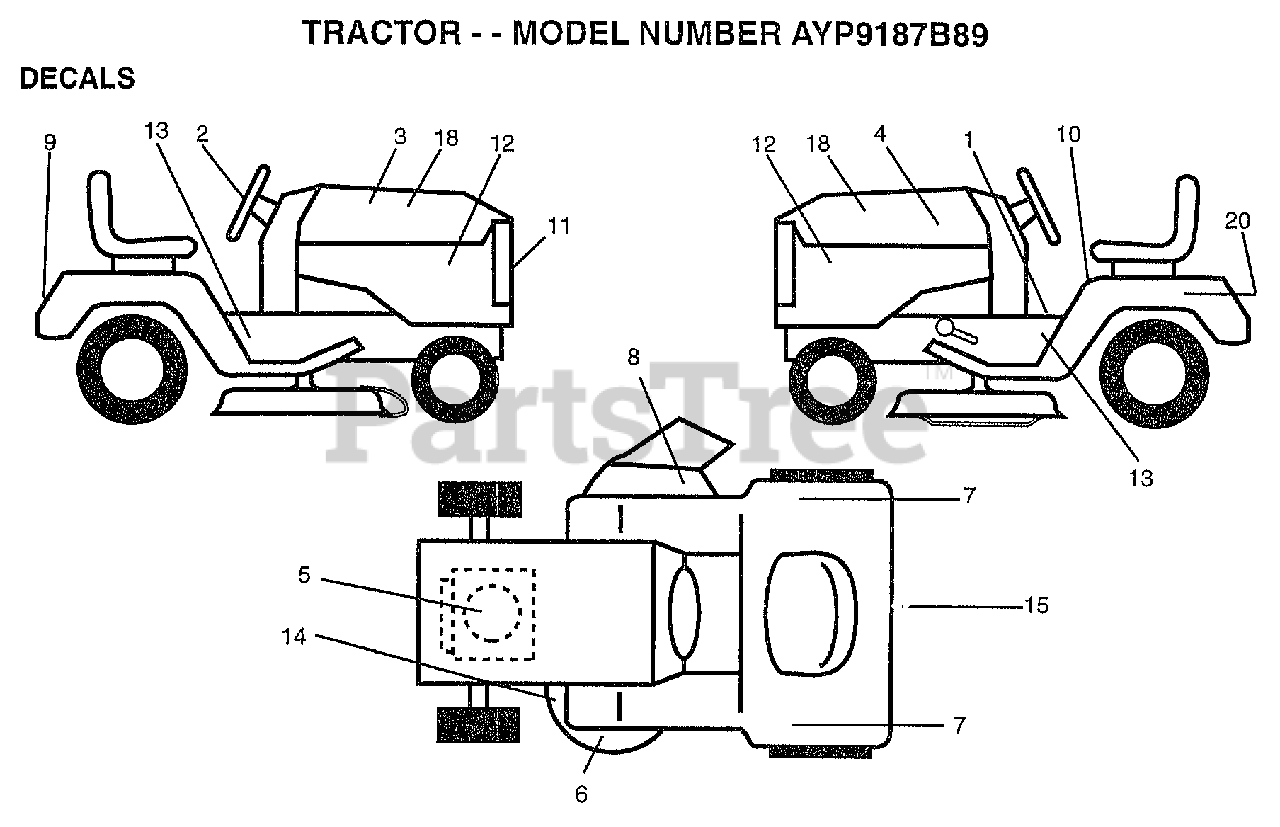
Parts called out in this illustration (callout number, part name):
1	"DEAL-OPER,INST."
2	DECAL STEER WHL
3	DECAL HOOD RH
4	DECAL HOOD LH
5	DECAL, ENGINE
6	DECAL DECK MULCH
7	DECAL.FENDER.AUTO
8	DECAL DECK WIZ +
10	"DECAL DANGER,FEND"
11	DECAL.LENS.WIZARD
12	DECAL PANEL SIDE
13	"DECAL.CHASSIS.42"""
14	"DECAL-SCHEM,BELT"
15	DECAL DRAWBAR LH
18	NAMEPLATE.HD.WIZA
20	DECAL.BATRY.3-3908
